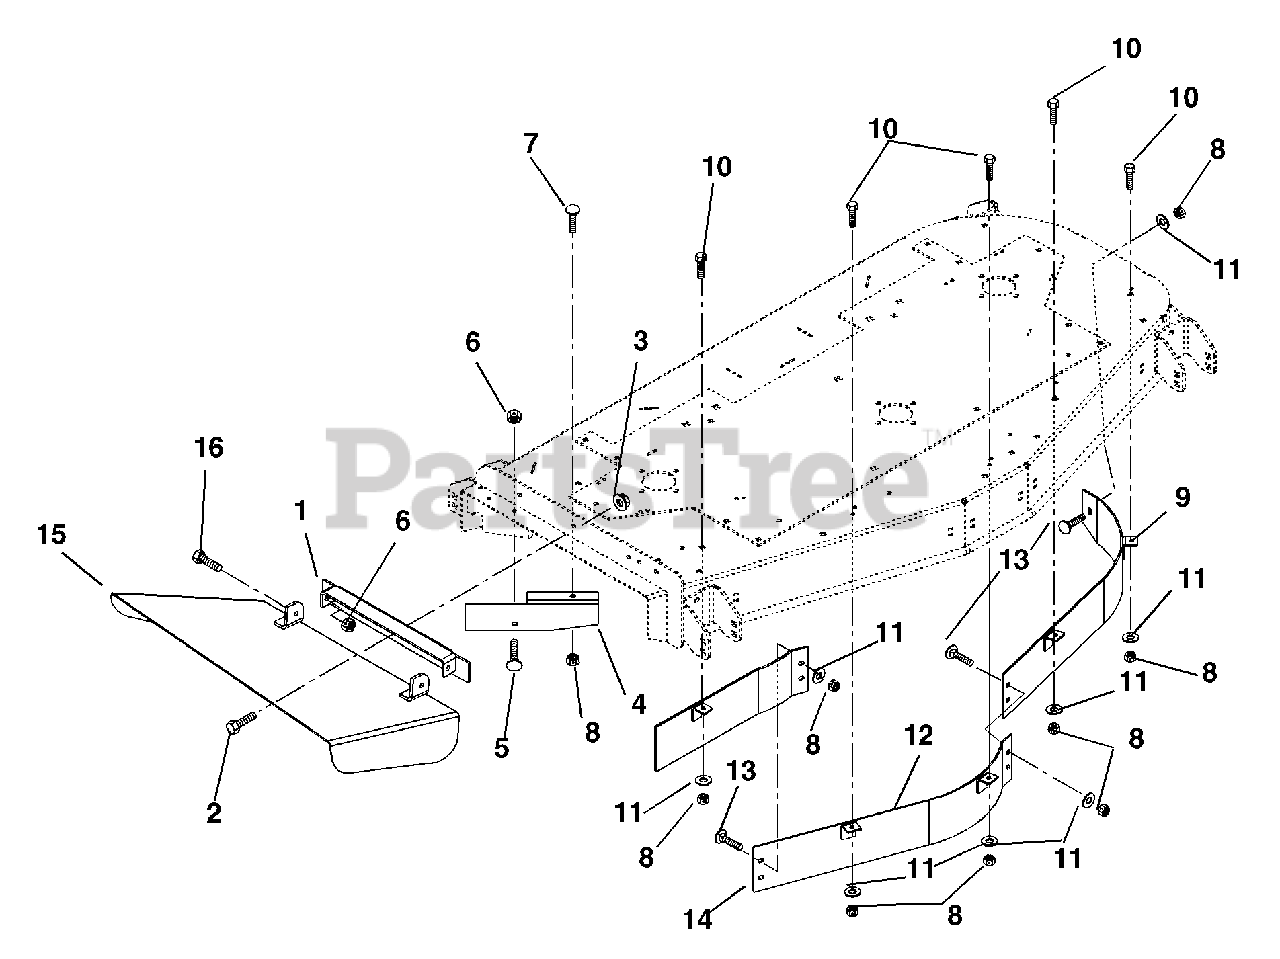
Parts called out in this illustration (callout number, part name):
1	Weldment, Discharge Chute Bracket
2	Bolt-Hex .38-16 x 1.00 Grade 5
3	Nut-Locking-Flange .38-16
4	Deflector, 60
5	Bolt-Round Head Square Neck .38-16 x 1.00 Grade 2
6	Nut-Locking-Center .38-16
7	Bolt-Round Head Square Neck .31-18 x 1.00 Grade 5
8	Nut-Locking-Nylon .31-18
9	Weldment, 60" Left Hand Baffle-Upper
10	Bolt-Hex .31-18 x 1.00 Grade 5
11	Washer-Flat-Steel .312 x .734 x .065
12	Weldment, 60" Center Baffle-Up
13	Bolt-Round Head Square Neck .31-18 x .75 Grade 5
14	Weldment, 60" Right Hand Baffle-Upper
15	Weldment, Discharge Chute 60"
16	Bolt-Hex .38-16 x 1.00 Grade 5
17	60" Discharge Cover
18	60" Mulch Kit
